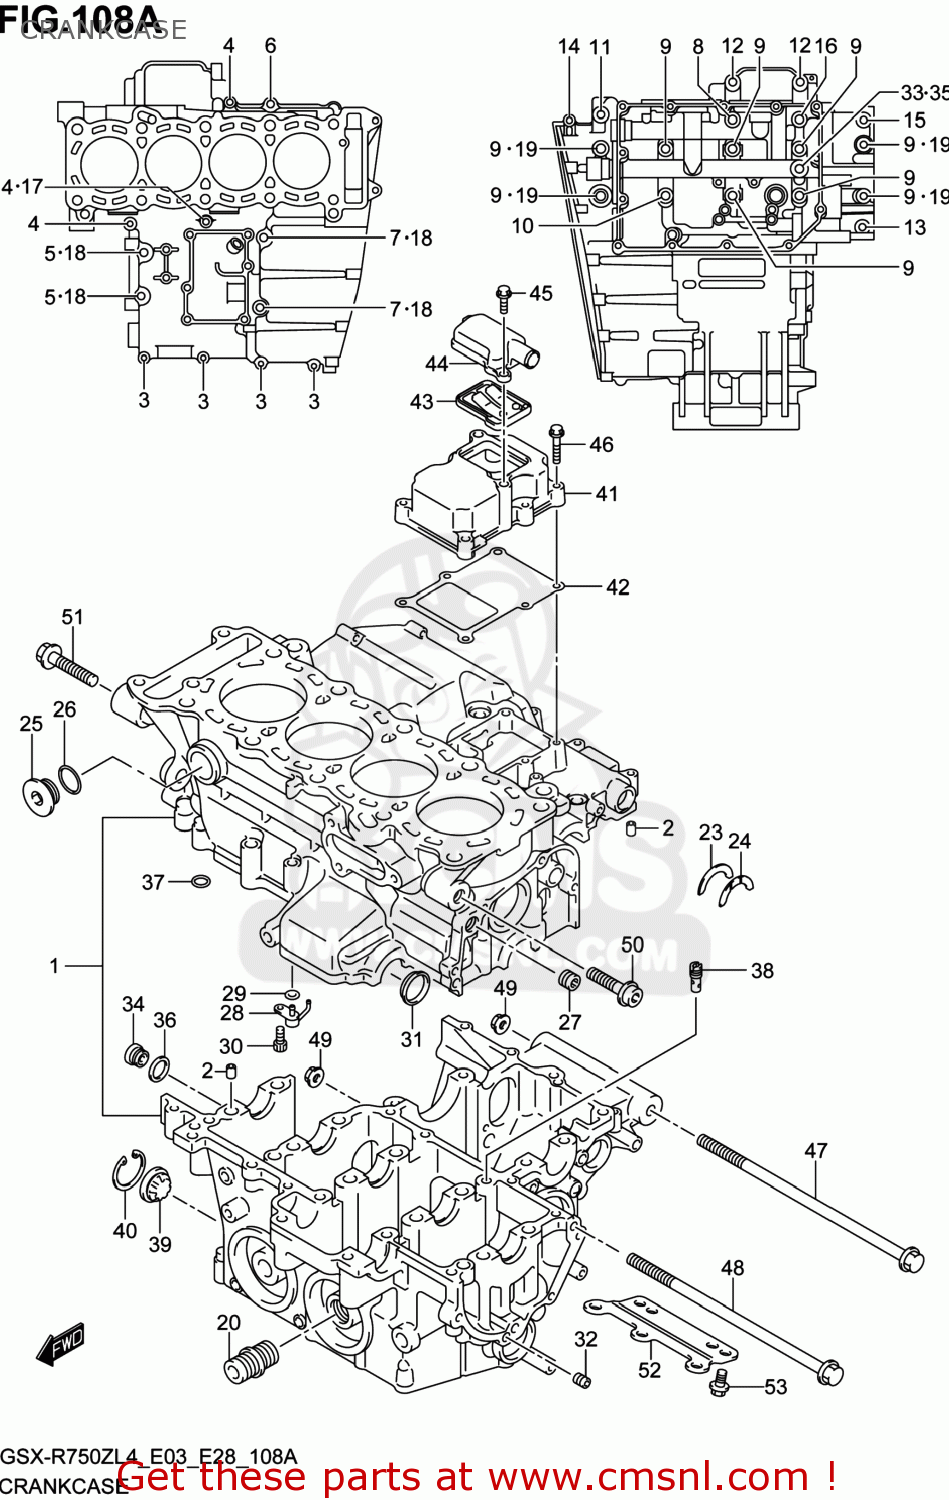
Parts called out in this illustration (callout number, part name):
1	CRANKCASE SET
2	PIN,CRANKCASE
3	BOLT
4	BOLT
5	BOLT
6	BOLT
7	BOLT
8	BOLT(8X105)
9	BOLT(9X95)
10	BOLT(9X80)
11	BOLT
12	BOLT(8X55)
13	BOLT
14	BOLT
15	BOLT
16	BOLT
17	GASKET(5.8X13X1.2) (NAS)
18	GASKET(8.2X14X1) (NAS)
19	GASKET(10.2X20X2).3 (NAS)
20	UNION,OIL STAND
21	O RING(D:1.9,ID:99.5)
22	BOLT(6X20)
23	BEARING,CRANK THRUST(GREEN)
24	BEARING,CRANK THRUST(RED)
25	PLUG,WATER JACKET
26	O RING(D:3.1,ID:19.4)
27	JET,OIL GALLERY(3.6)
28	JET,PISTON COOLING
29	O RING(D:1.2,ID:4)
30	BOLT(6X12)
31	PLUG
32	PLUG(1/8PT,H:5.5)
33	PLUG(L:12)
34	PLUG
35	GASKET(12.1X16.2X3.7) (NAS)
36	GASKET(16X22X2) (NAS)
37	O RING(D:1.9,ID:7.8)
38	JET(140)
39	LENS,OIL LEVEL CHECK
40	CIRCLIP
41	COVER,BREATHER
42	GASKET,BREATHER COVER (NAS)
43	VALVE ASSY,BREATHER REED
44	COVER,BREATHER REED VALVE
45	BOLT
46	BOLT
47	BOLT(10X215)
48	BOLT(10X205)
49	NUT
50	BOLT(10X45)
51	BOLT(10X55)
52	PLATE,CRANKCASE LWR
53	BOLT(6X10)
